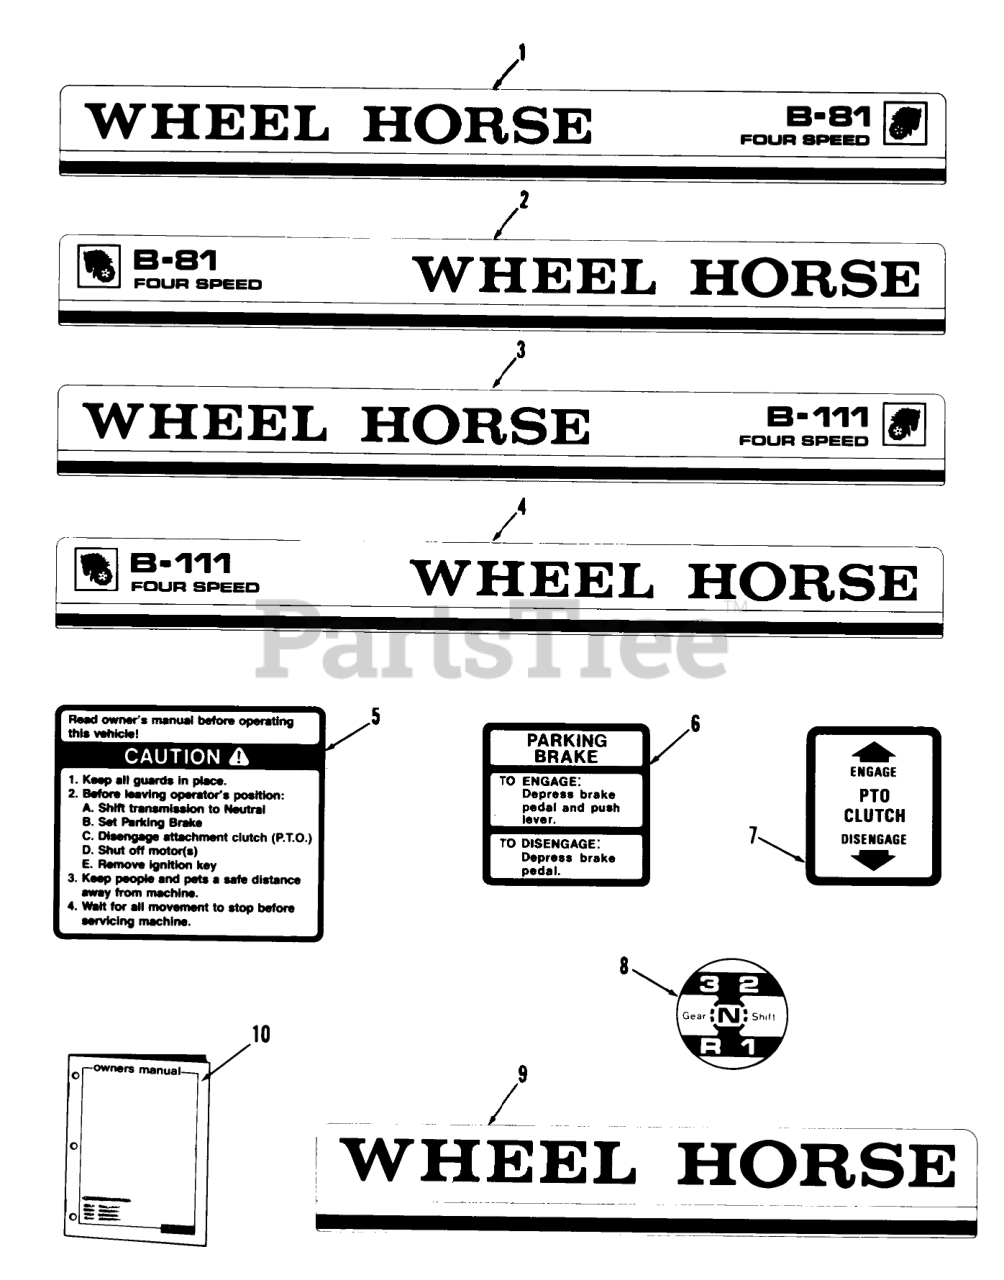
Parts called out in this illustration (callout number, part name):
1	Decal-Hood B-81 RH
2	Decal-Hood B-81 LH
3	Decal-Hood B-111 RH
4	Decal-Hood B-111 LH
5	DECAL-CAUTION
6	Decal Parking Brake
7	DECAL-PTO CLUTCH
8	DECAL-SHIFT
9	Decal-Rear
10	Owner-s Manual
